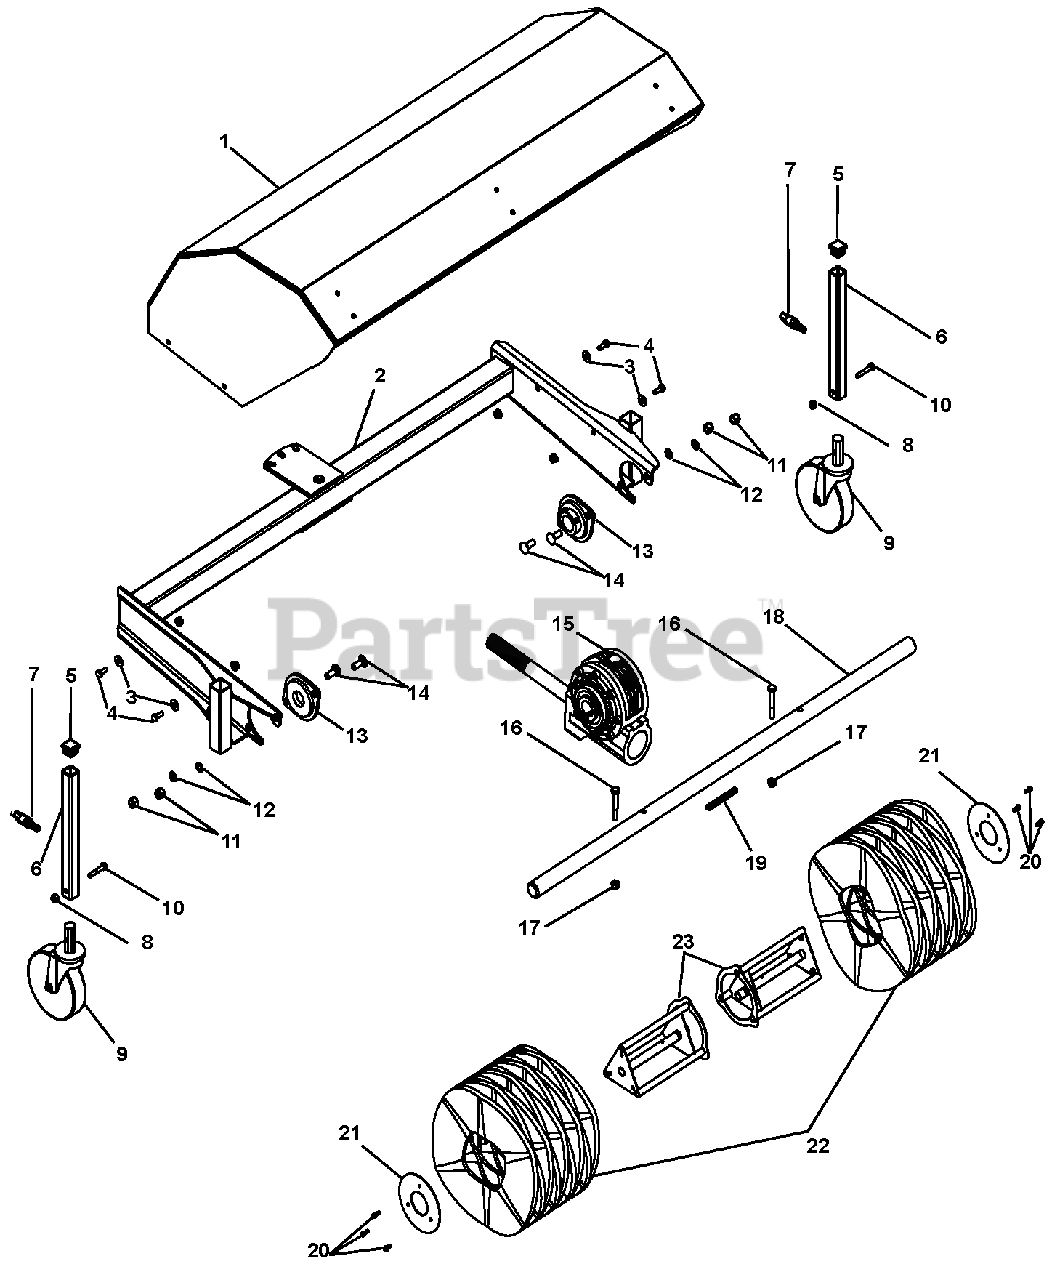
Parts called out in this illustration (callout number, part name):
1	Hood, 36" Brush with Decals
2	Frame, Brush-W.U. 3’ Brush
3	Washer, Flat Steel, .312 x .734 x .065
4	Bolt-Hex, .25-20 x .76 Grade 5
5	Plug, Square-1" Plastic
6	Tube, Square-1 x 1
7	Black Knob
8	Locking Nut, Nylon .250-20
9	Caster Wheel, 5" x 3/4"
10	Bolt-Hex, .25-20 x 1.50 Grade 5
11	Locking Nut, Nylon .38-16
12	Washer, SAE .38
13	Bearing, 1 1/8" Flangette
14	Bolt-Round Head Square Neck .38-16 x 1.00 Grade 5
15	Aluminum Gearbox
16	Bolt-Hex .31-18 x 2.25 Grade 5
17	Locking Nut, Nylon .312-18
18	Thru Shaft, 1-1/8 x 3’
19	Key, Square .25 x .25 x 3
20	HHCS, Serrated Flange .38-16 x 1
21	End Retainer Plate
22	Kit, Bristle-Set of 10
23	Core, Weldment 3’
